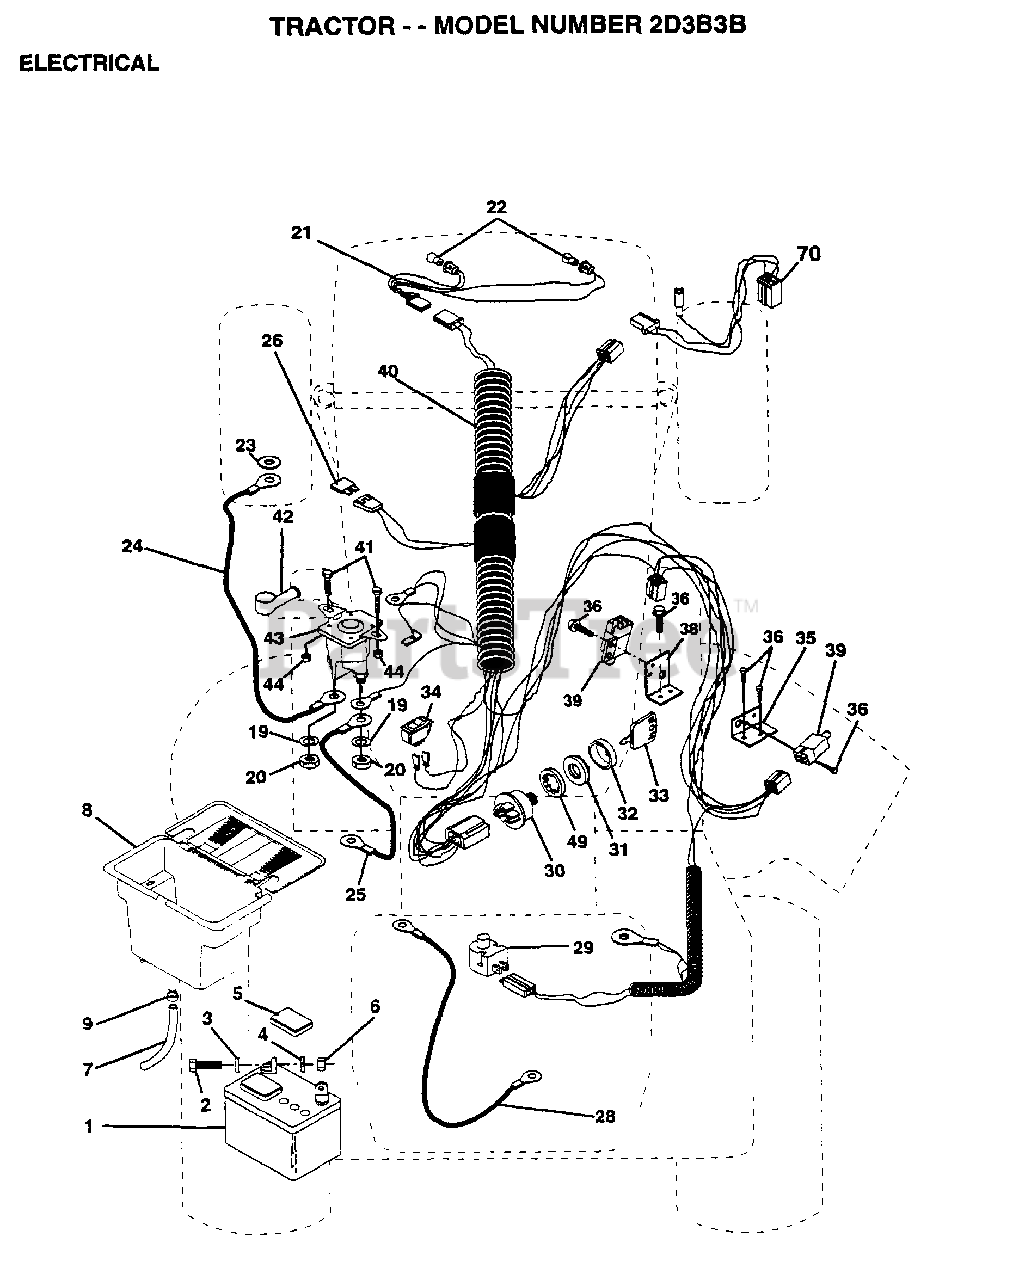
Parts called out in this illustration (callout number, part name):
2	BOLT LT
3	WASHER
4	LOCKWASHER
5	"CAP,BATTERY "
7	TUBE T
9	HOSE CLAMP T
20	NUT
21	"HARNESS,LIGHT SOC"
22	HEADLAMP BULB
23	LOCKWASHER
24	"CABLE T, BATTERY"
26	FUSE HYT
28	CABLE T
29	SWITCH SEAT
32	COVER KEY SWITCH
33	KEY MLD GEN DELTA
34	SWITCH LT
35	BRACKET LT
36	SCREW
38	BRACKET SWITCH IN
39	SWITCH INTERLOCKT
40	HARNESS IGN DASH
41	BOLT HXHD FIN
44	NUT HXKEP 1/4X20
49	LOCKWASHER
70	HARNESS ENG DUAL
